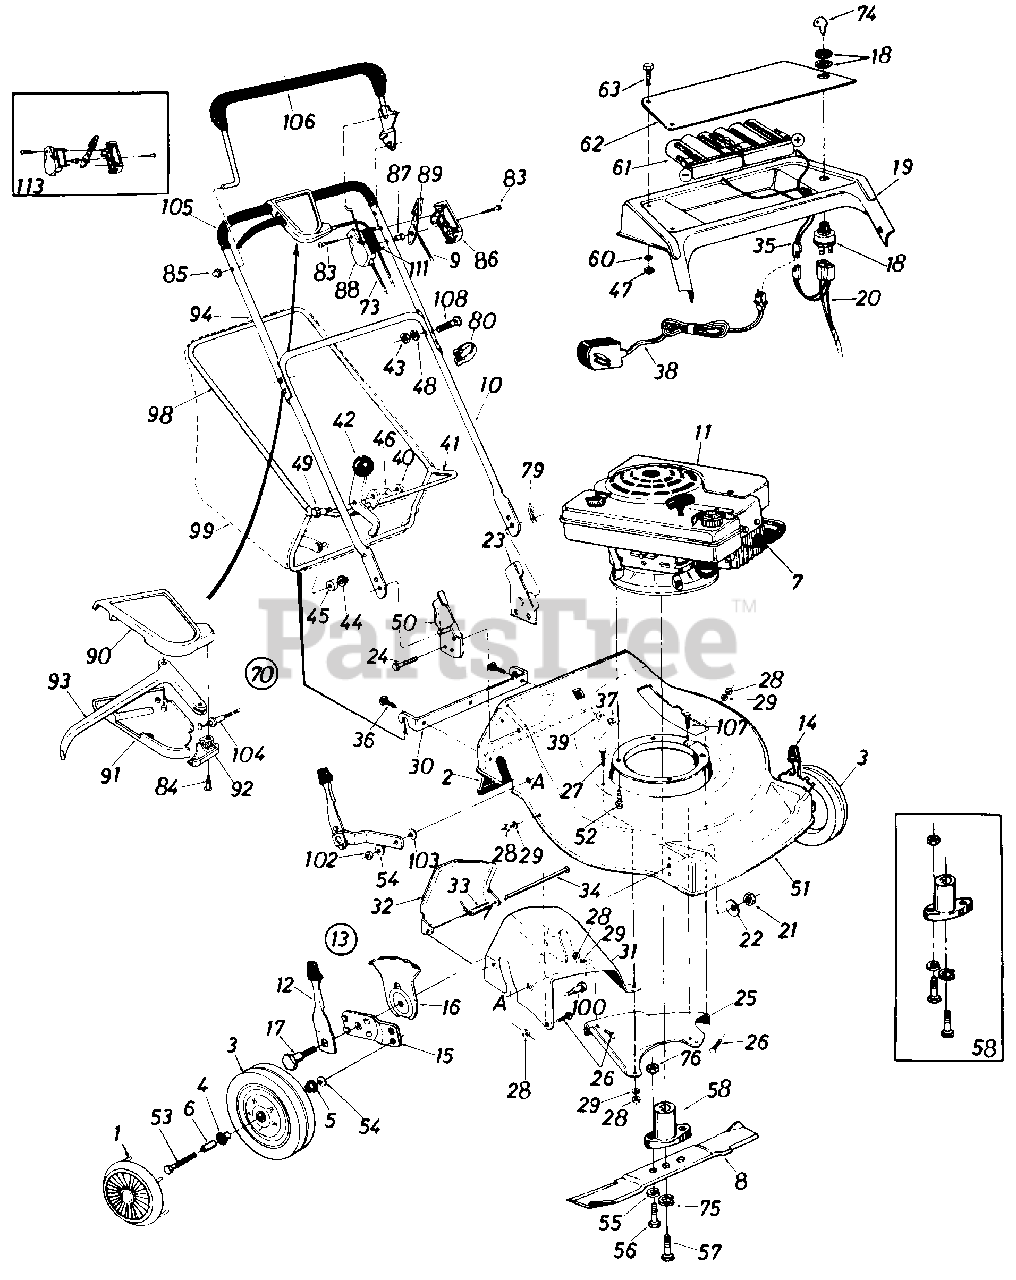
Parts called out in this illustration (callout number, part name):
1	Hub Cap Plastic
2	Rear Flap Ass'y.
3	Front Wheel Ass'y. Comp.
4	Bearing 3/8 I.D.
5	Bearing 112" I.D.
6	Spacer
7	Spark Plug Boot
8	20" Blade
9	Throttle Control Wire 43"
10	Lower Handle
12	Spring Lever Ass'y. w/Knob
13	Height Adjust. Ass'y. R.H.
14	Height Adjust. Ass'y. L.H.
15	Pivot Bar
16	Index Plate
17	Shld. Bolt .50" Dia. x .375"
18	Ignition Switch
19	Handle Panel
20	Wire Harness
21	Hex Nut 3/8-16 Thd.
22	Bell-Wash. .39" I.D. x 1.38" O.D.
23	Handle Brk't. Ass'y. L.H.
24	Hex Wash. Hd. AB-Tap Scr. 1/4" x .62" Lg.
25	Rear Baffle L.H.
26	Carriage Bolt 1/4-20 x .50"
27	Hex Bolt 1/4-20 x .88" Lg.
28	Hex Nut 1/4-20 Thd.
29	L-Wash. 1/4" I.D.
30	Grass Catcher Hitch Brk't.
31	Rear Chute Baffle Ass'y.
32	Chute Door
33	Torsion Spring
34	Hinge Pin .250" Dia. 7.88" Lg.
35	Battery Pack Lead
36	Carriage Bolt 1/4-20 x .75"
37	Sems Nut 1/4-20 Thd.
38	Battery Charger
39	Fl-Wash. .285" I.D. x 1.25"
40	Hex Nut 5/16-18 Thd.
41	Grass Catcher Lower Frame Ass'y.
42	Cam Lever Ass'y.
43	Hex Nut 5/16-18 Thd.
44	Push Nut 3/8 Rod
45	Plastic Roller
46	L-Wash 5/16" I.D.
47	Hex Nut #8-32 Thd.
48	L-Wash. 5/16" I.D.
49	Shld. Bolt .437" Dia. x .180"
50	Handle Brk't. Ass'y. R.H.
53	Axle Bolt
54	Bell-Wash. .44" I.D. x .88"
55	L-Wash. 5/16" I.D.
56	Hex Bolt 5/16-24 x 1.00" Lg. (Grade 8)
57	Hex Bolt 3/8-24 x 2.25" Lg. Grade 5
58	Blade Adapter Kit
60	External L-Wash. #8 I.D.
61	Battery Pack
62	Battery Plate
63	Fl-Hd. Phil. Scr. #8-32 x .38" Lg.
70	Clutch Control Housing Com p.
73	Clutch Cable 55" Lg.
74	Ignition Key
75	L-Wash. 3/8 I.D. H eavy D u ty
76	Hex Nut 5/16-24 Thd.
79	Intern. Cot. Pin 5/16" Dia.
80	Cable Tie
83	Truss Mach. Scr. #12 x 1.50"
84	Flat "C"-Sunk Hd. Scr. #10 x 1.0" Lg.
85	Cap Speed Nut 5/16" Rod
86	Control Panel Half
87	Control Disc Pin
88	Clutch Panel Half
89	Throttle Control Lever
90	Control Cover Half Upper
91	Control Cover Half Lower
92	Cable Mtg. Cap
93	Control Lever
94	Upper Handle
98	Grass Catcher Upper Frame
99	Grass Bag
100	Shld. Bolt .500" Dia. x .685"
102	Hex Jam Nut 3/8-16 Thd.
103	Bell-Wash. .400" I.D.
104	Clutch Cable 50"
106	Blade Clutch Control Handle
107	Hex Wash. Hd. Self-Tap Scr. 1/4-20 x .75" Lg.
108	Curved Carr. Bolt 5/16-18 x 1.38" Lg.
111	Control Label
113	Control Housing Comp.
